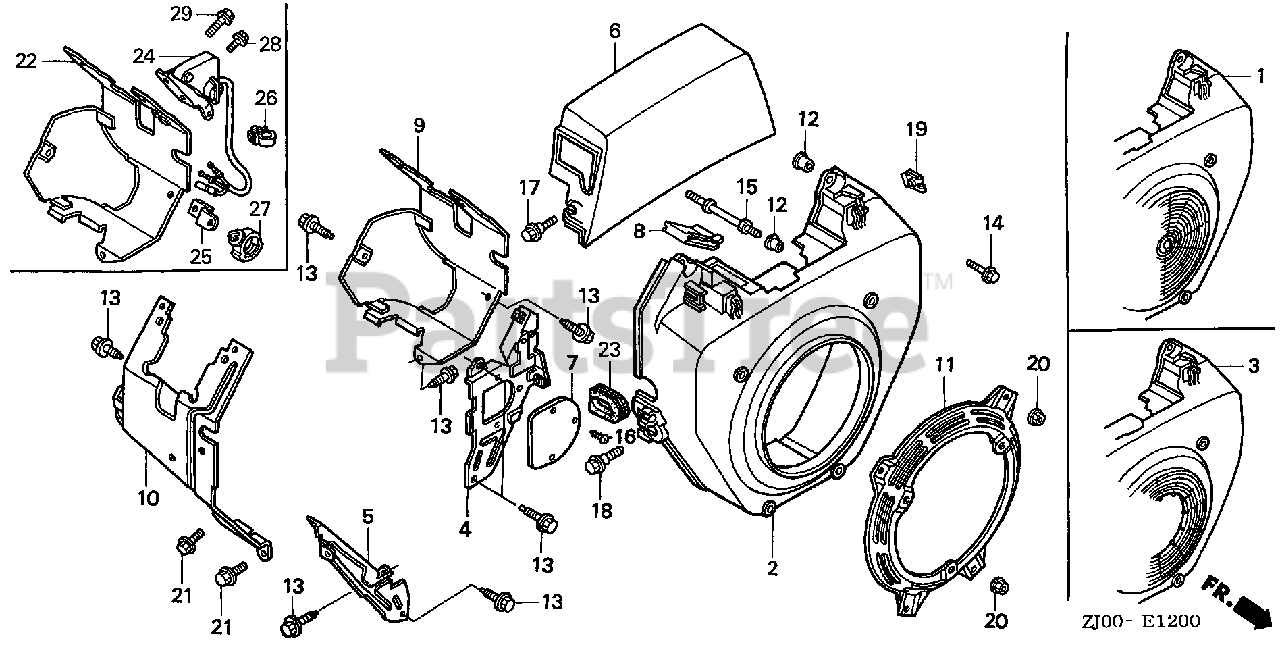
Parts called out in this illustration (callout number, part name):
1	COVER, FAN *R280* (POWER RED)
4	PLATE, SIDE (L. SIDE)
5	PLATE, SIDE (R. SIDE)
6	HOOD, FAN COVER
8	PLUG, FAN COVER HOLE
9	SHROUD (L. SIDE)
10	SHROUD (R. SIDE)
12	COLLAR B, TAILLIGHT
13	BOLT, FLANGE (6X12) (CT200)
14	BOLT, FLANGE (6X23) (CT200)
15	BOLT, STUD (6X73)
17	BOLT, FLANGE (6X20)
18	BOLT, FLANGE (6MM) (BLACK)
19	NUT, SPRING (6MM)
20	NUT, FLANGE (6MM)
21	BOLT, FLANGE (6X8)
